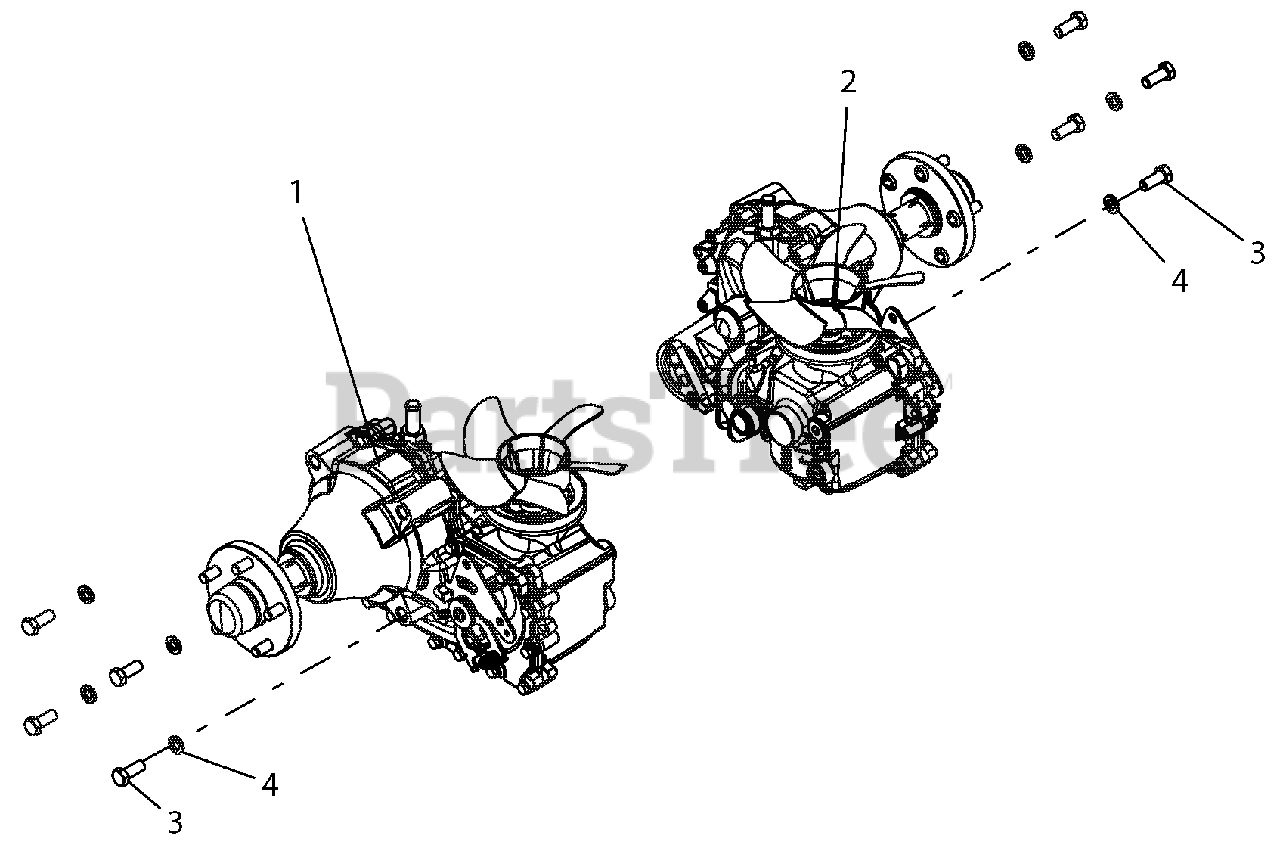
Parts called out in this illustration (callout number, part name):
1	TRANS, R.H. HG ZT-5400
2	TRANS, LH HG ZT-5400
3	BLT-HEX .50-13X1.25 GR5 YWZC
4	WSHR-LK .50X.125 REG YWZC
